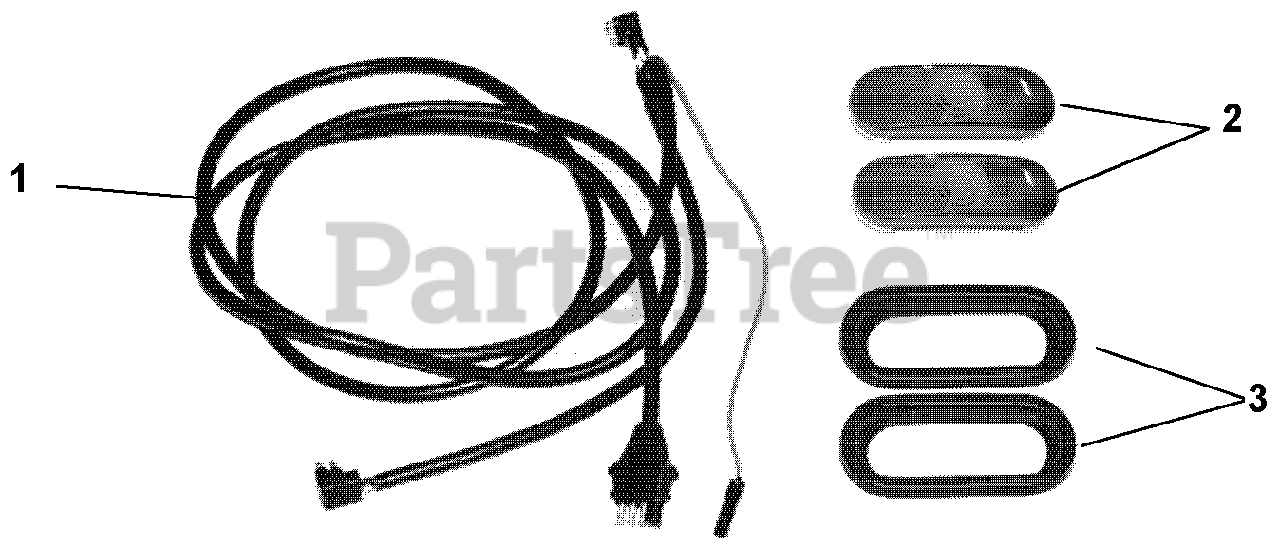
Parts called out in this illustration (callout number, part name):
1	WIRE HRNS,TRAILER LIGHT KIT
2	TAIL LIGHT HOUSING W/ BULB
3	GROMMET, TAIL LIGHT MOUNTING
